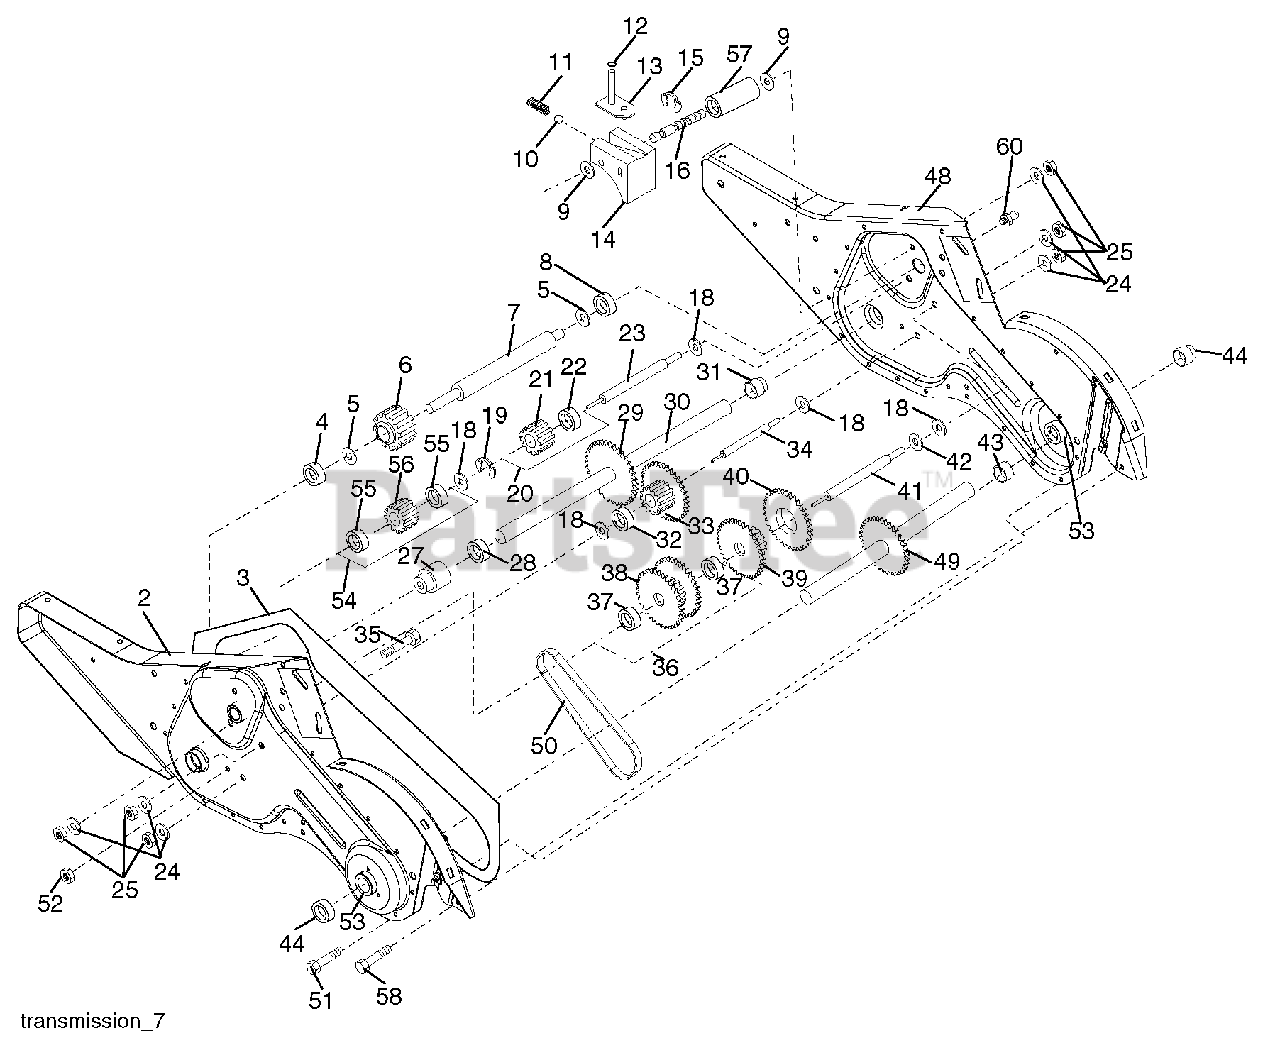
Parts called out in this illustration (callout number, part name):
1	Transmission Assembly
2	Gearcase, L.H. w/Bearing
3	Gasket, Gearcase
4	Bearing, Needle
5	Washer, Thrust 5/8 x 1.10 x 1/32
6	Pinion, Input
7	Shaft, Input
8	Bearing, Needle
9	Washer, Seal
10	Ball, Steel
11	Spring, Shift, Fork
12	O-Ring
13	Arm, Shift
14	Fork, Shift
15	Ring, Klip
16	Shaft, Shift
18	Washer
19	Ring, Klip
20	Gear, Assembly, Reverse Idler
21	Gear, Reverse Idler
22	Bearing, Needle
23	Shaft, Reverse Idler
24	Washer, Lock 7/16
25	Nut, Hex 7/16-20
27	Bearing, Shaft, Ground Drive L.H.
28	Spacer 0.765 x 1.125 x 1.23
29	Chain #35-50 Pitch
30	Ground Shaft Assembly
31	Bearing, Shaft, Ground Drive R.H.
32	Spacer 0.70 x 1.00 x 1.150
33	Sprocket and Gear Assembly
34	Shaft, Reduction (2nd)
35	Screw, Whiz, Lock 5/16-18 x 3-1/2
36	Sprocket Assembly w/Bearing
37	Bearing, Needle
38	Sprocket, Tine
39	Gear, Cluster, Red 1st & 2nd
40	Gear, Reverse
41	Shaft, Reduction (1st)
42	Washer, Thrust
43	Spacer 1.01 x 1.75 x 0.760
44	Seal Asm. OIl
48	Gearcase, R.H. w/Bearing
49	Shaft, Tine
50	Chain, Roller #50-50 Pitch
51	Screw 1/4-20 x 1/2
52	Nut, Hex 5/16-18
53	Bearing Kit, Tine Shaft
54	Gear, DRT Idler w/Bearing
55	Bearing, Needle
56	Gear, DRT Idler
57	Spacer, Split .52 x .64 x 1.04
58	Screw 1/4-20 x .875
60	Fitting Grease
61	Spacer 1.015 x 1.50 x .650
61	Grease, Plastilube #1
